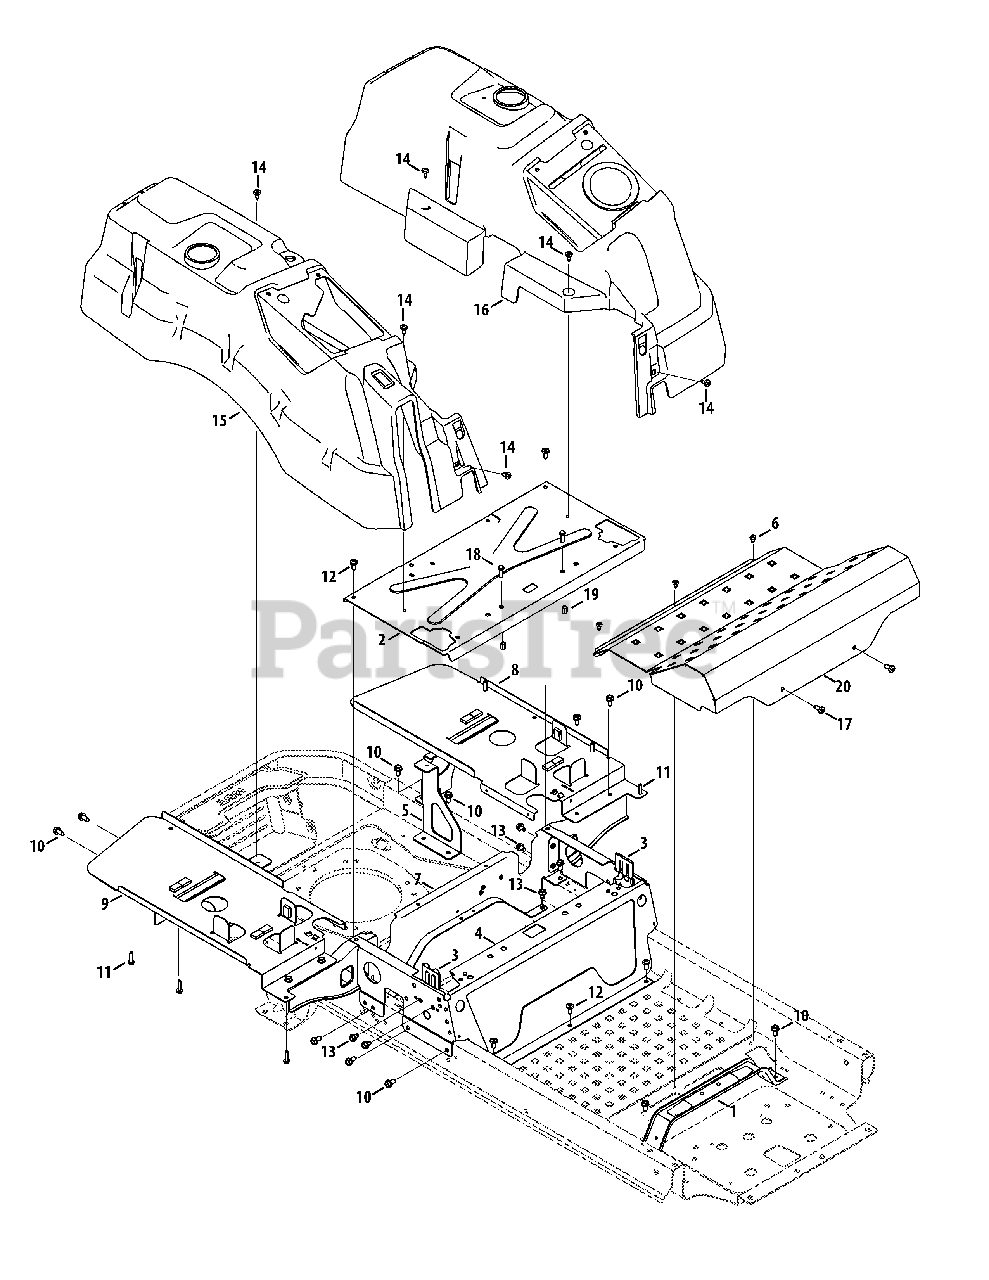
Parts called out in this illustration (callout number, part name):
1	Steering Support Bracket
2	Seatbox Plate
3	Lapbar Brace Bracket
4	Seat Frame
5	Rear Support Bracket, LH
5	Rear Support Bracket, RH
6	Screw, 1/4-20 x .50
7	Rear Seatbox Brace
8	Tank Support Plate, LH
9	Tank Support Plate, RH
10	Hex Washer Screw, 5/16-18 x .750
11	Hex Washer Screw, 5/16-14 x 1.00
12	Self Tapping Screw, 5/16-18 x .750
13	Hex Washer Screw, 5/16-18 x .50
14	Shoulder Screw, 1/4-20
15	RH Console
16	LH Console
17	Screw, 5/16-18 x .75
18	Hex Cap Screw, 5/16-18 x 1.00
19	Nut, 5/16-18
20	Floor Board, Fab
